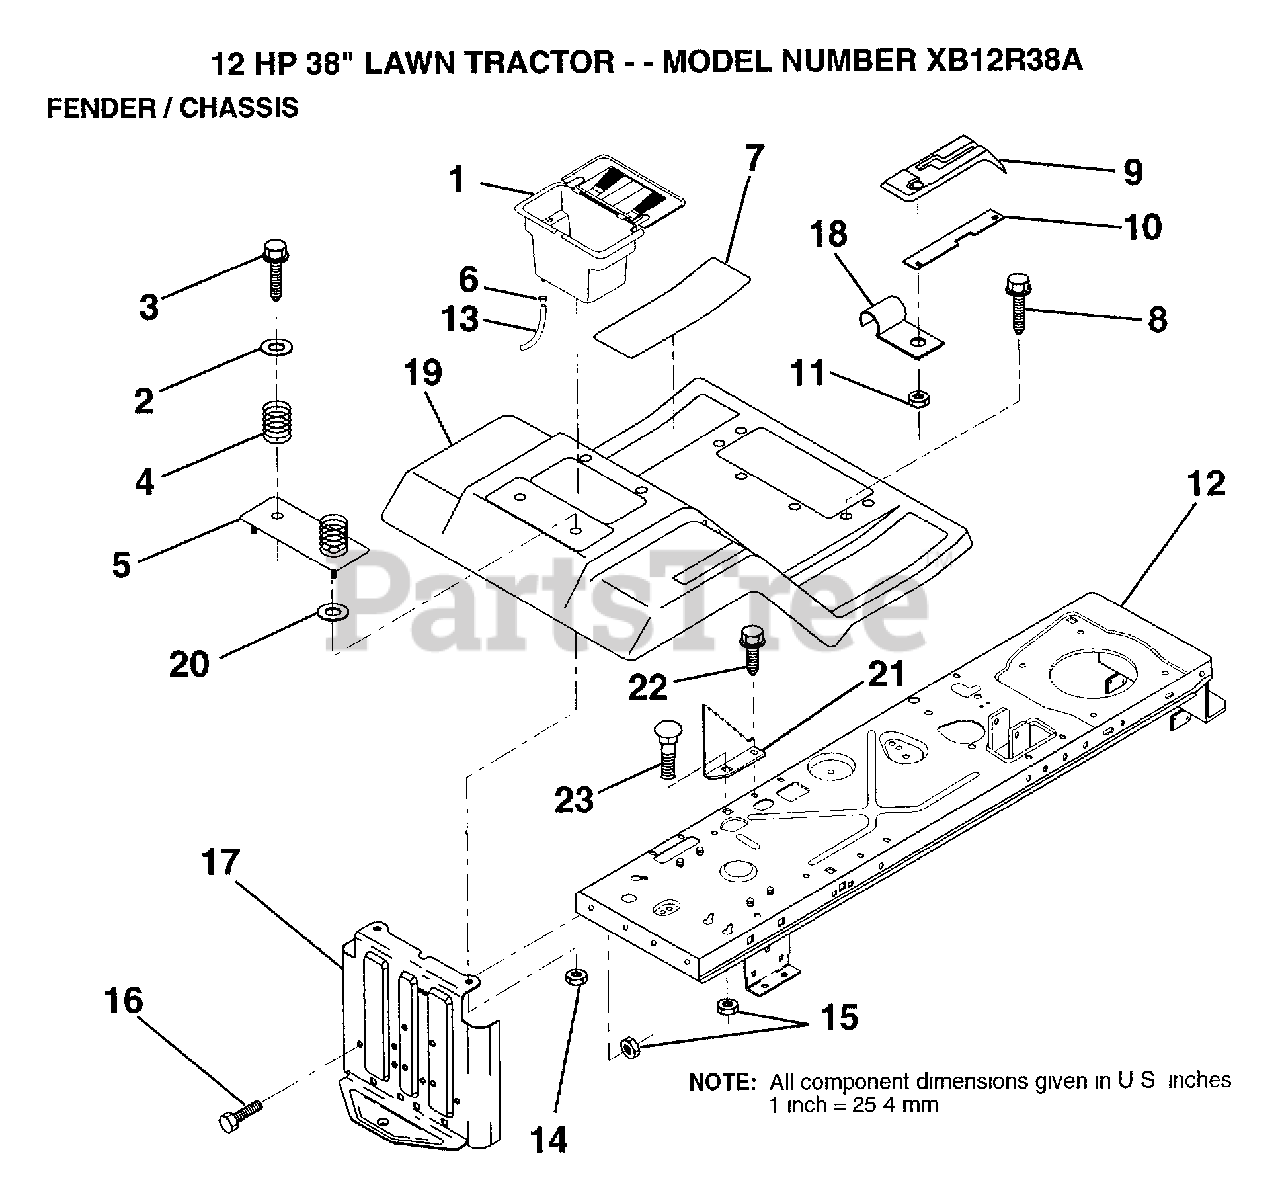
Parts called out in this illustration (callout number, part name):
2	WASHER
3	SCREW
4	SPRING COMPRESSIO
5	"PLATE,FENDER"
6	HOSE CLAMP T
7	FOOTREST PAD
8	SCREW
10	"SHIFT LOCK, BAR"
11	NUT
14	NUT
16	BOLT
17	DRAWBAR
18	"CLIP,INSULATOR"
22	SCREW LT
